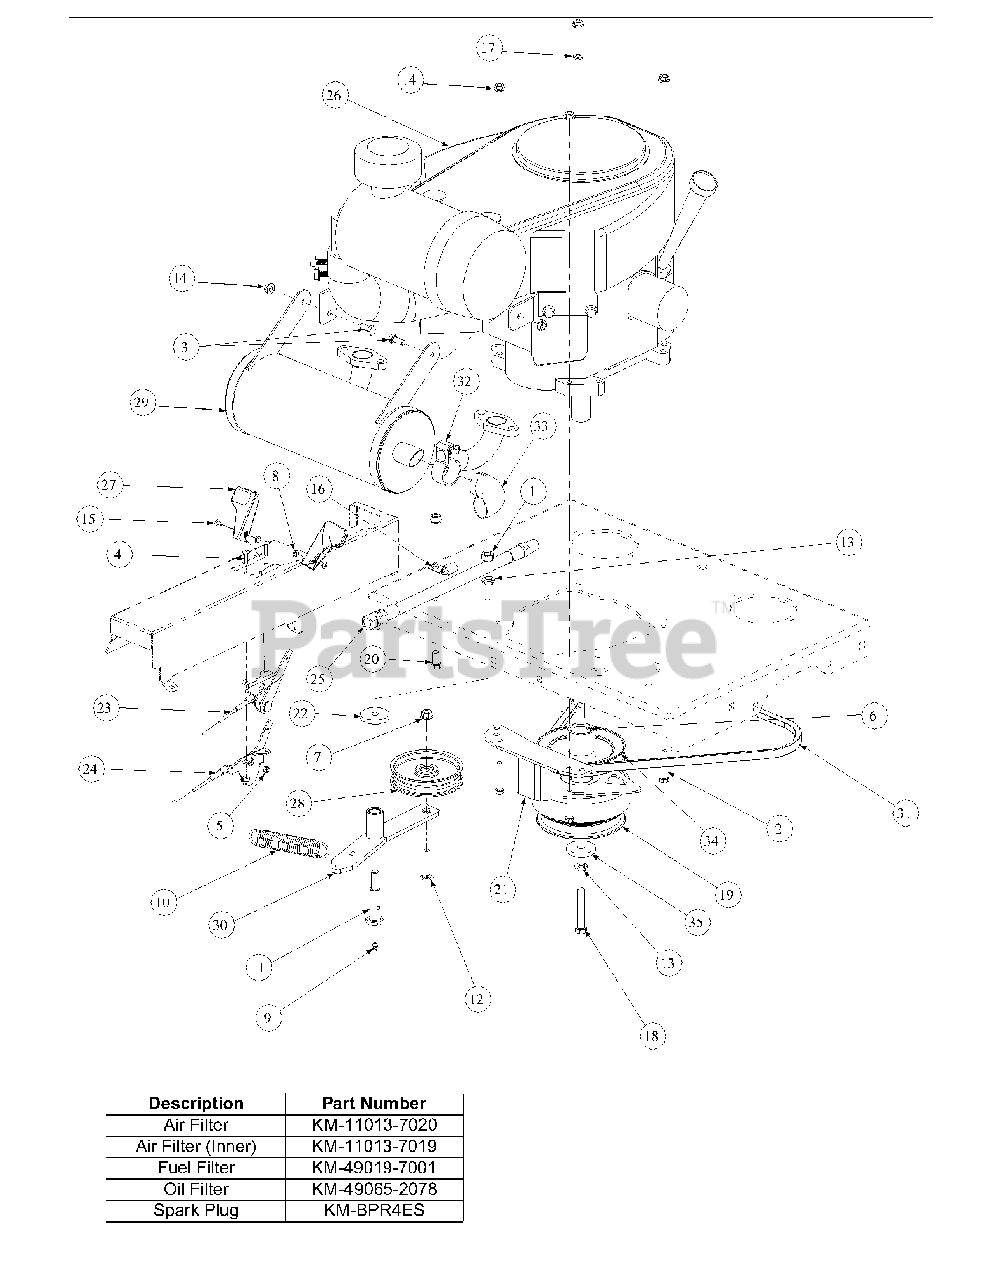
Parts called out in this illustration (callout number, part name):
1	Hex Nut, 7/16-14
2	HHCS, 5/16-18, 1-3/4
3	Hex Cap Screw, 5/16-18 x 3/4
4	Round Hd. Machine Screw, 10-32 x 3/4
5	Lock Nut, Nylon Insert, 10-32
6	Key, 1/4 x 1/4 x 3
7	Flange Lock, Hex Nut, 3/8-16
8	Nut Washer, W/Star, 8-32
9	Grease Fitting, 1/4-28 x 3/16
10	Extension Spring, 1.0 OD x 5.125
11	Shoulder Screw, 7/16-14
12	Hex Carriage Screw, 3/8-16, 1.75
13	Lock Washer, 7/16
14	Hexflange Lock Nut, 5/16-18
15	Machine Screw, 8-32, .375
16	Clip, Heat Shield Cable
17	Flat Washer, 5/16
18	Capscrew, 7/16-20 x 2.50
19	Clutch Brake, 1.125 ID
20	Hex Cap Screw, 3/8-16, .750
21	Retainer Clutch Assembly, Ogura
22	Flat Washer, 7/16 ID x 1.75 OD x .25
23	Choke, Control Cable, 43.0
24	Throttle, Control Cable, 39.0
25	Oil Drain Hose
26	25HP Twin Engine, Kawasaki
27	Control Throttle Knob
28	Flat Pulley with Flanges
29	Muffler Accessory, Kawasaki
30	Engine Idler Arm Assembly
30	Bearing
31	V Belt, A Section x .47.3
32	Tube Clamp, 1.375
33	Muffler Accessory Exhaust Tube
34	Pump Drive Pulley
35	Flat Washer, 7/16 ID x 1.75 OD x .25
